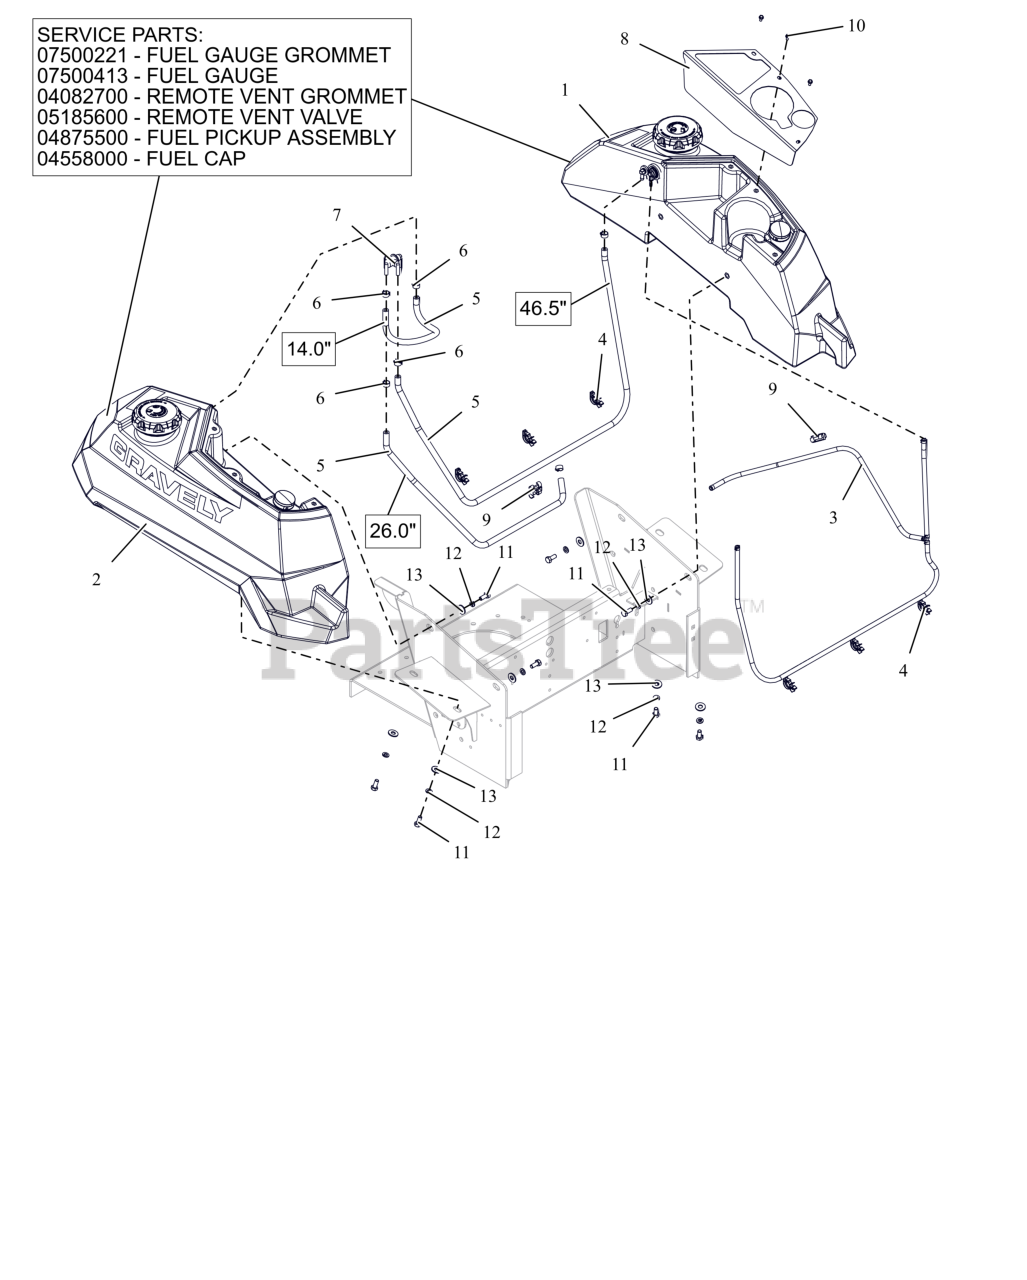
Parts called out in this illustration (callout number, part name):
1	ASM, LH - PT100 FUEL TANK
1	GROMMET, FUEL GAUGE
1	GAUGE, REMOTE SEALED FUEL
1	GROMMET, REMOTE VENT NITRILE
1	VALVE, COMBINATION VENT 3/16
1	ASSM,LRG TANK FUEL PICKUP LINE
1	CAP, FUEL VENTIN AUTOLOCK
2	ASM, RH - PT100 FUEL TANK
2	GROMMET, FUEL GAUGE
2	GAUGE, REMOTE SEALED FUEL
2	GROMMET, REMOTE VENT NITRILE
2	VALVE, COMBINATION VENT 3/16
2	ASSM,LRG TANK FUEL PICKUP LINE
2	CAP, FUEL VENTIN AUTOLOCK
3	ASM, VAPOR LINE
4	WIRE CLIP
5	1 INCH OF HOSE, .25 LOW-PERM BULK GAS
6	CLAMP, FUEL LINE
7	VALVE, FUEL
8	PT100 CUPHOLDER PANEL - RED
9	CLIP, T, .38-.50
10	SCR-MCH 10-24X.38 HWHSTAINLESS
11	BLT,HEX .31-18X.75 G5 ZCC
12	WSHR,LK-REG .312X.078 ZCC
13	WSHR,FLT .375X.875X.083 ZCC
